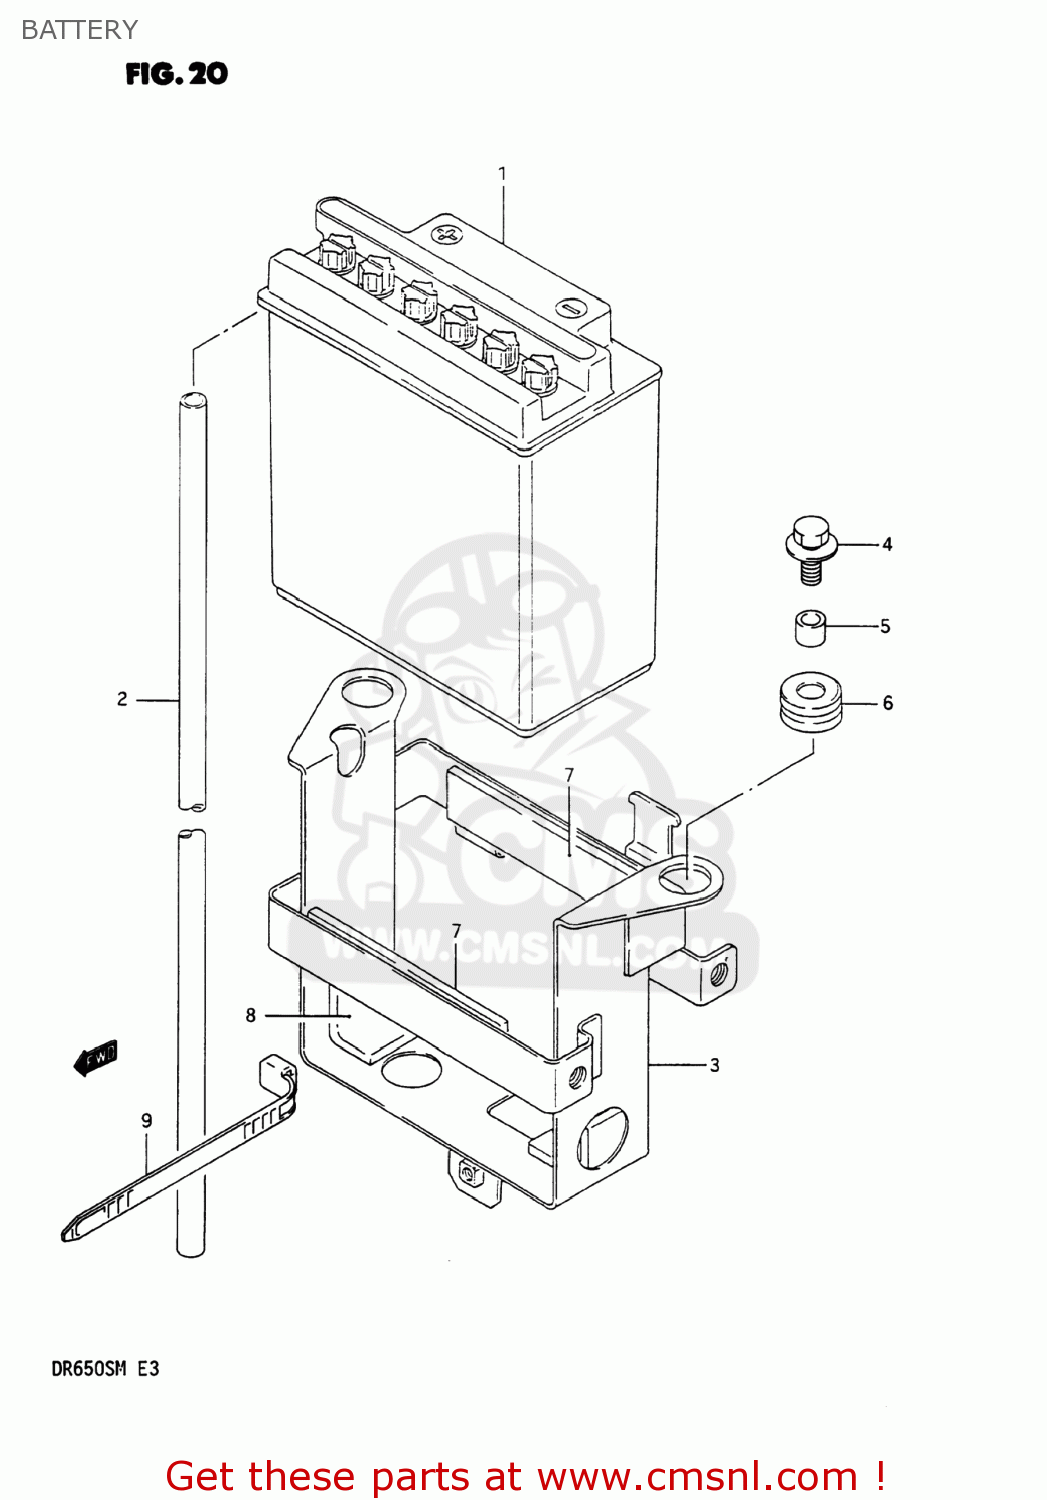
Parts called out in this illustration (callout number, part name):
1	BATTERY ASSEMBLY (12V)
2	HOSE,BATTERY EXHAUST
3	HOLDER,BATTERY
4	BOLT
5	SPACER(6.1X9X7.5)
6	CUSHION
7	PROTECTOR,20X9
8	PROTECTOR(30X80X2)
9	CLAMP(L:125)
